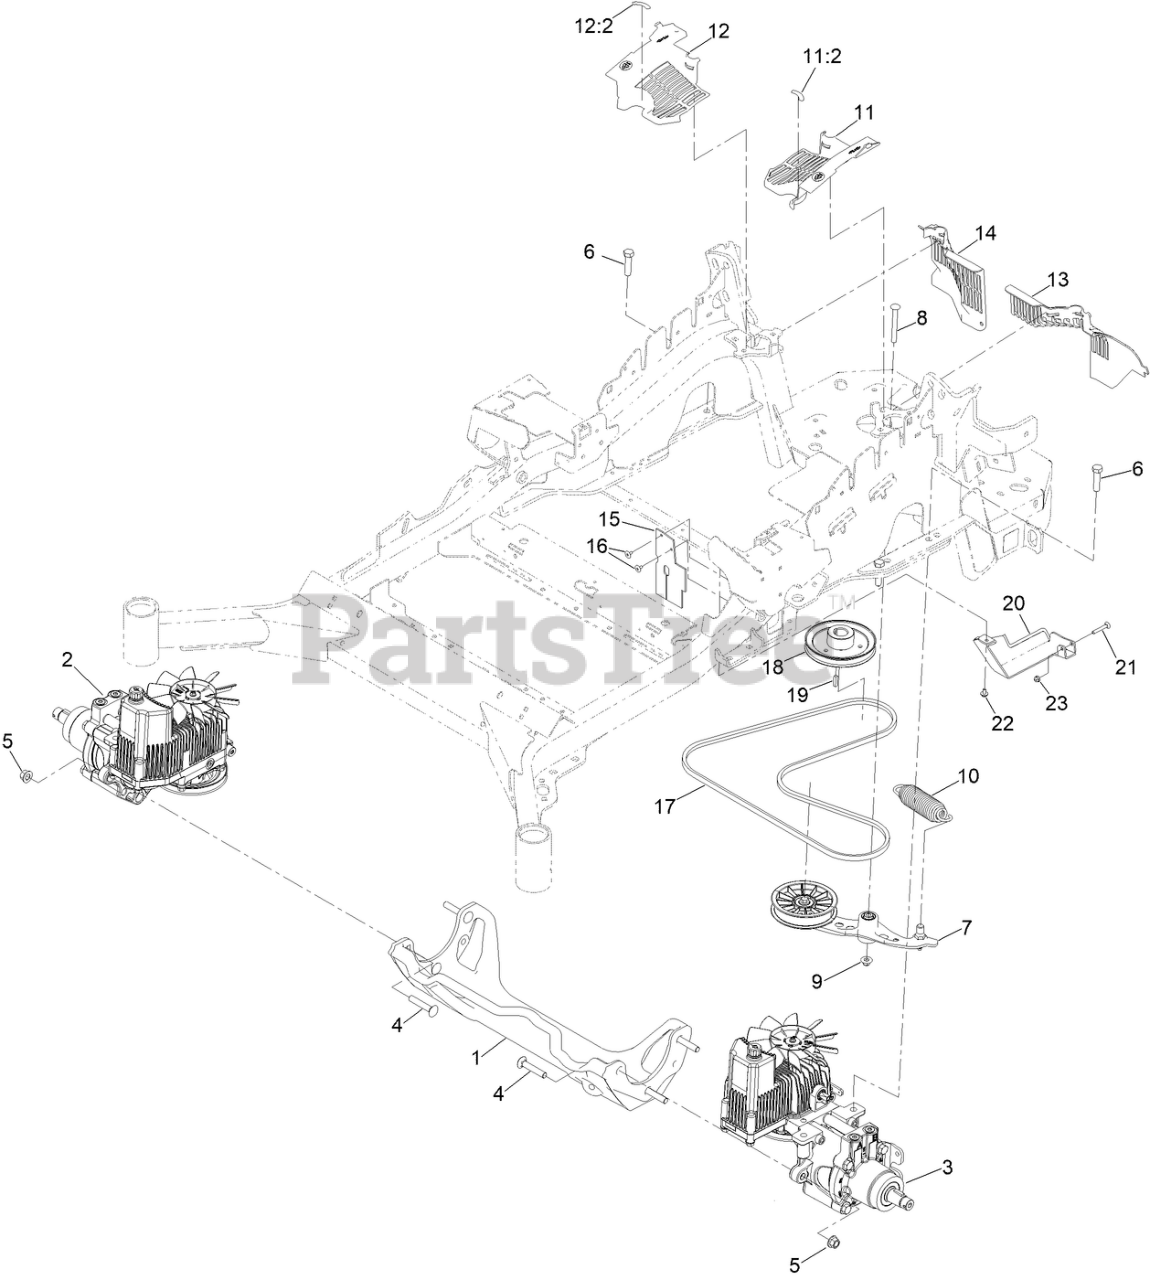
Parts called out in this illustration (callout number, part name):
1	CRADLE-HYDRO
2	HYDRO-RH
3	HYDRO-LH
4	SCREW-CARR
5	NUT-LOCK
6	SCREW-HH
7	PUMP IDLER ASM
8	BOLT-SHOULDER, CARRIAGE
9	NUT-FLANGE, NI
10	SPRING-EXTENSION
11	LH HYDRO GUARD ASM
11:2	DECAL-OIL, HYDRO
12	RH HYDRO GUARD ASM
12:2	DECAL-OIL, HYDRO
13	GUARD-HYDRO REAR, LH TRIM
14	GUARD-HYDRO, REAR (RH)
15	DEFLECTOR-AIR FLOW
16	RIVET-POP
17	BELT-V
18	SHEAVE
20	TANK GUARD WLDMNT
21	SCREW-CARR
22	SCREW AND WASHER ASM
23	NUT-HF
